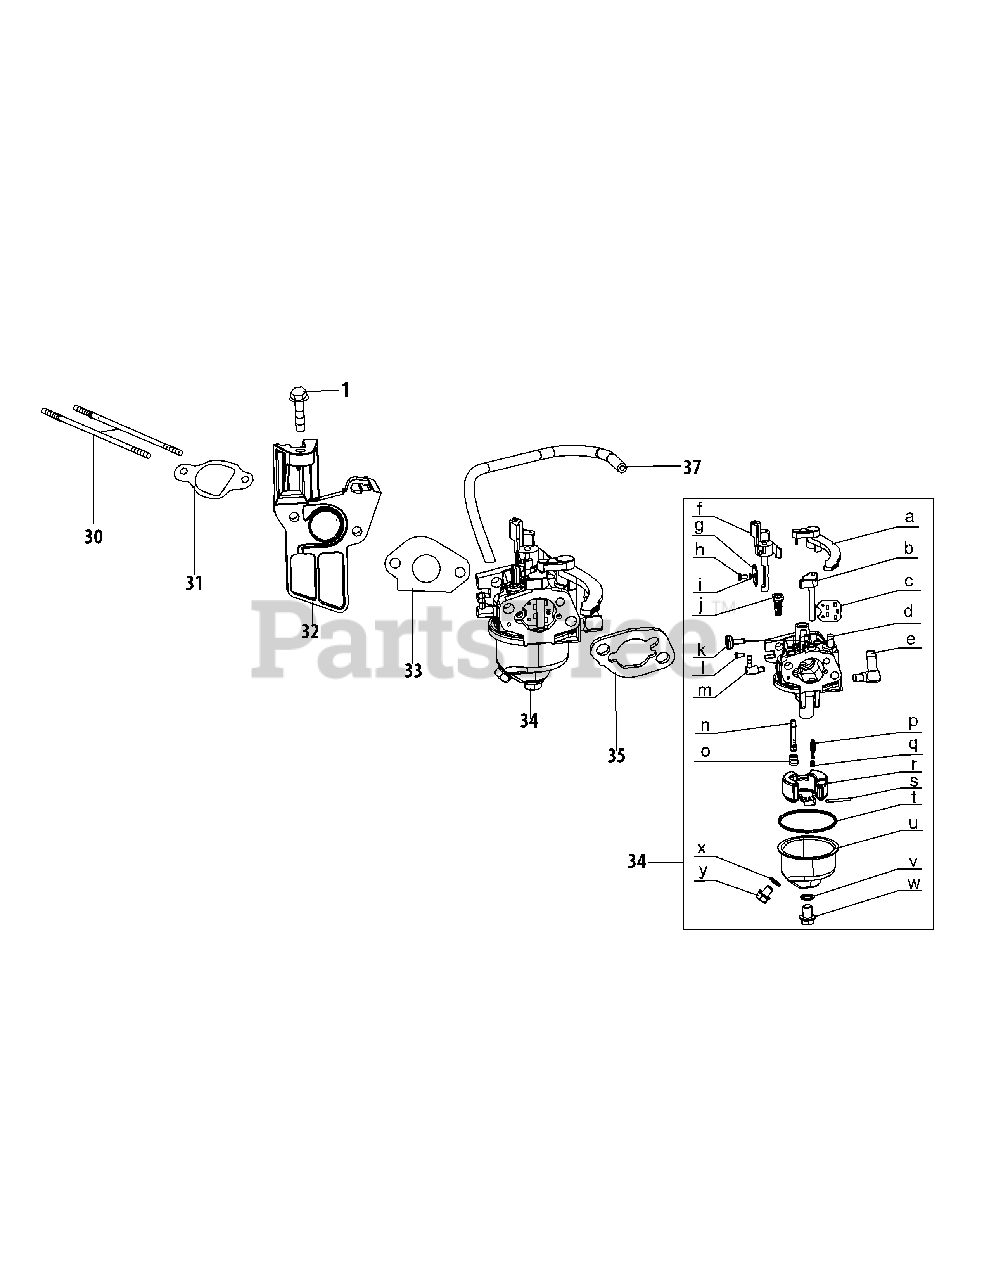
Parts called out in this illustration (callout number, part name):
1	Bolt M6×16
30	Stud M6×110
31	Gasket, Carburetor Insulator
32	Carburetor Insulator
33	Carburetor Gasket
34	Carburetor
35	Gasket,Air Cleaner
37	Fuel Hose 3.2×6.5×240
